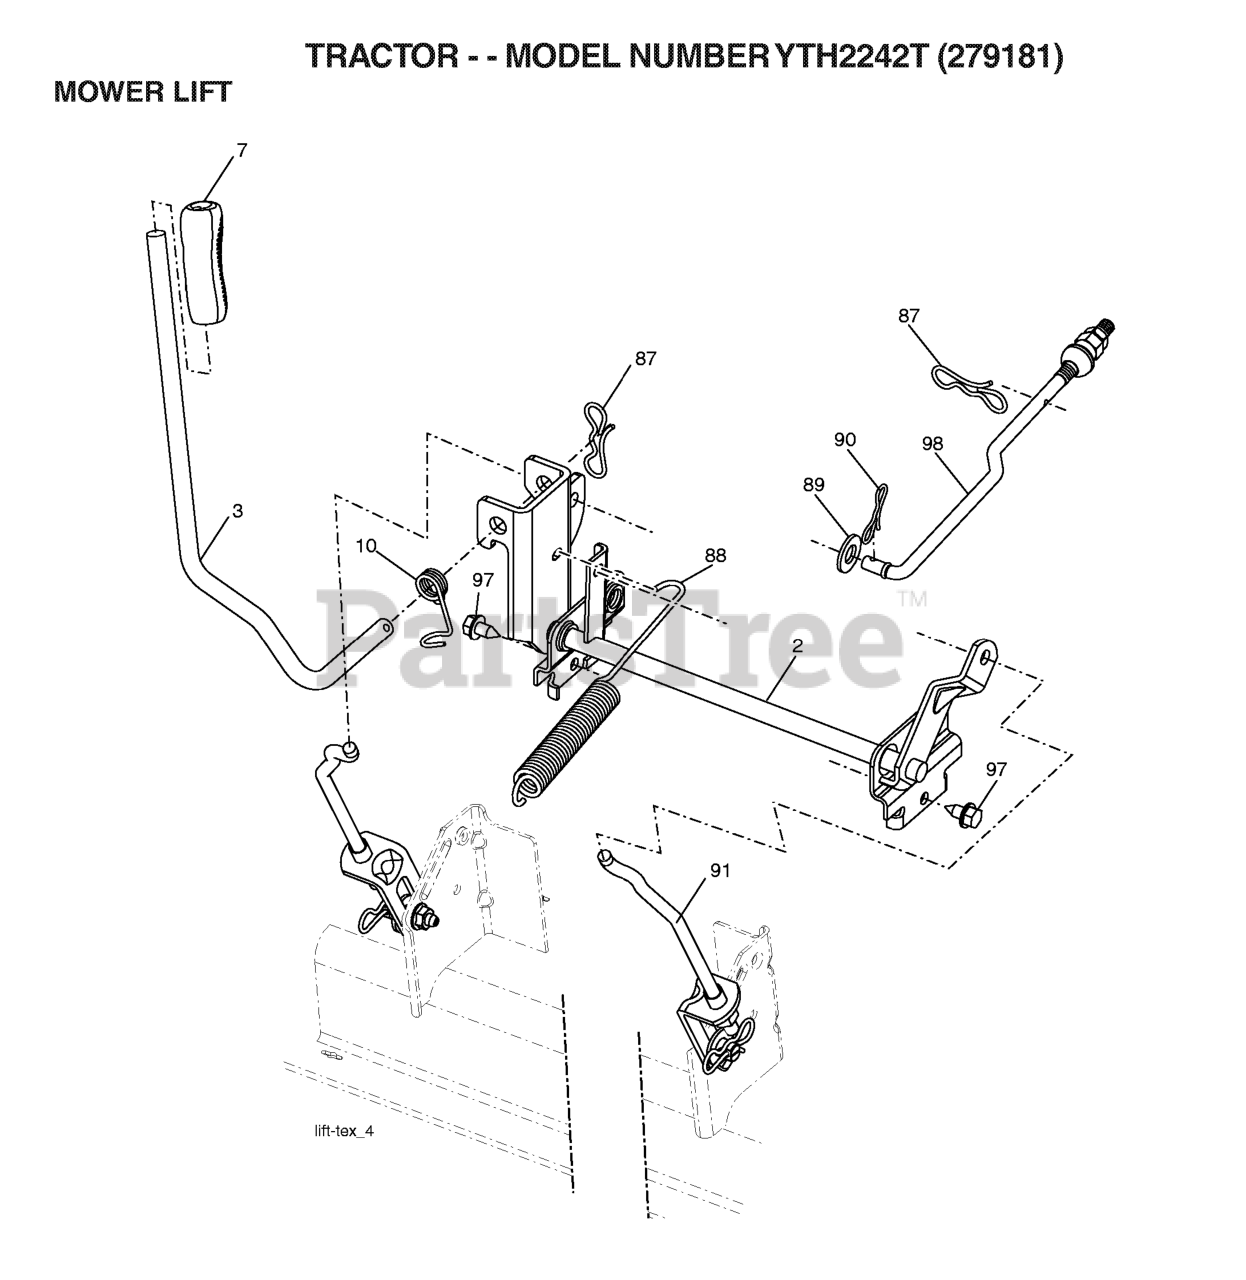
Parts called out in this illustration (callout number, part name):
2	SHAFT.ASM.LIFT.CROSS.H
3	LEVER.LIFT.HANDLE.LT
7	GRIP.LEVER.5625.ID
10	SPRING.TORSION.LIFT.HANDLE
87	PIN.COTTER.7/16.BOW TI.
88	SPRING.LIFT.ASSIST.LT
89	WASHER.CLEAR.ZINC
90	PIN.COTTER.5/16.BOW TI
91	LINK.ASM.LIFT.REAR
97	SCREW 3/8-16X3/4
98	LINK.ASM.SUSP.FRONT.MW
